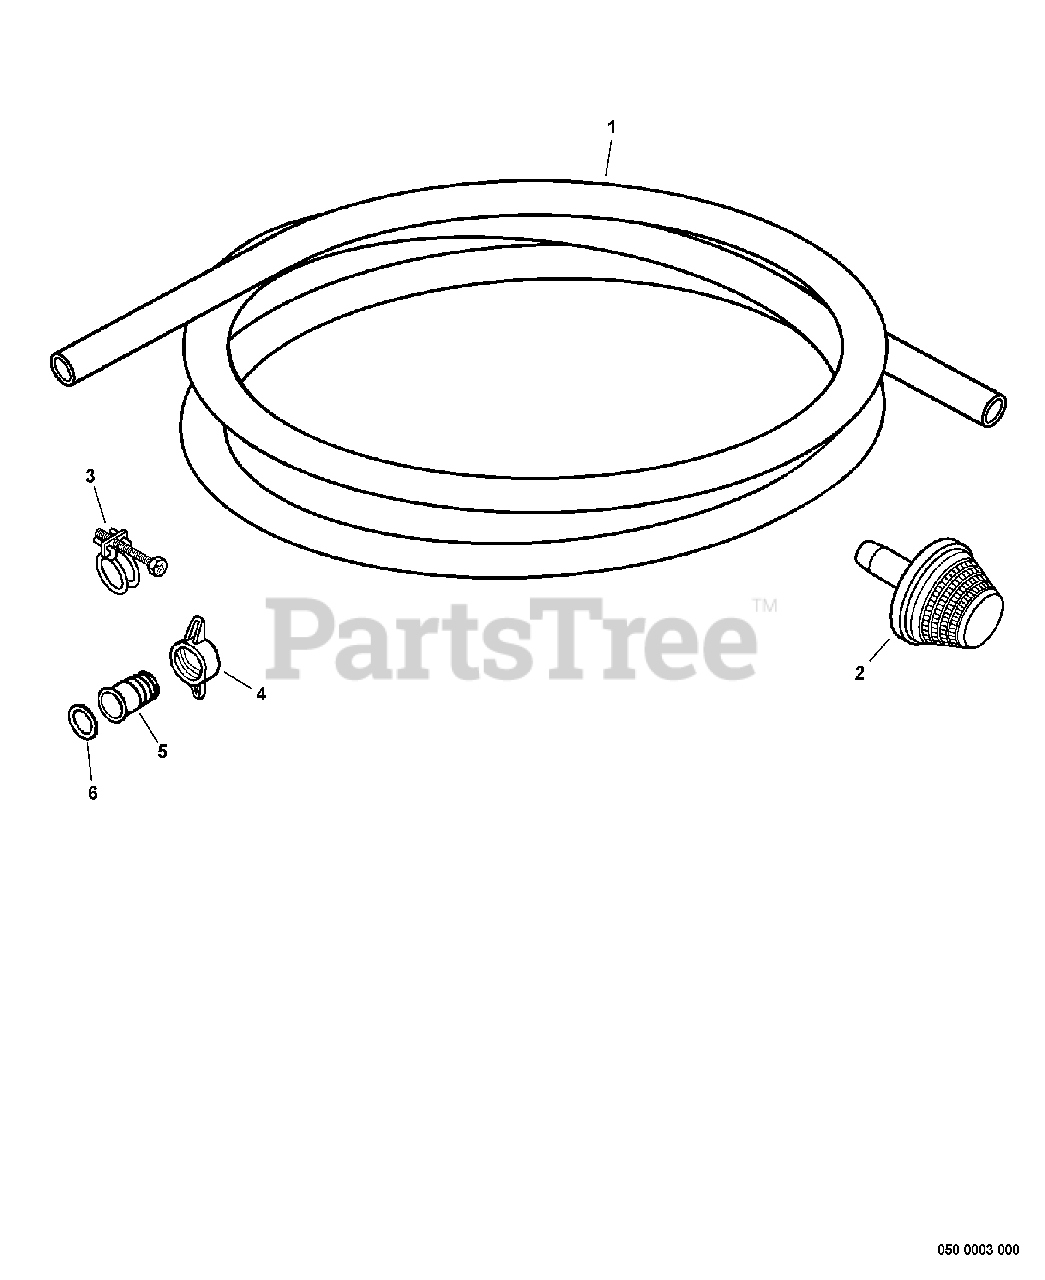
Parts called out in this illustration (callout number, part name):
1	HOSE, SUCTION - 1" X 10'
2	STRAINER, DEBRIS
5	NIPPLE
